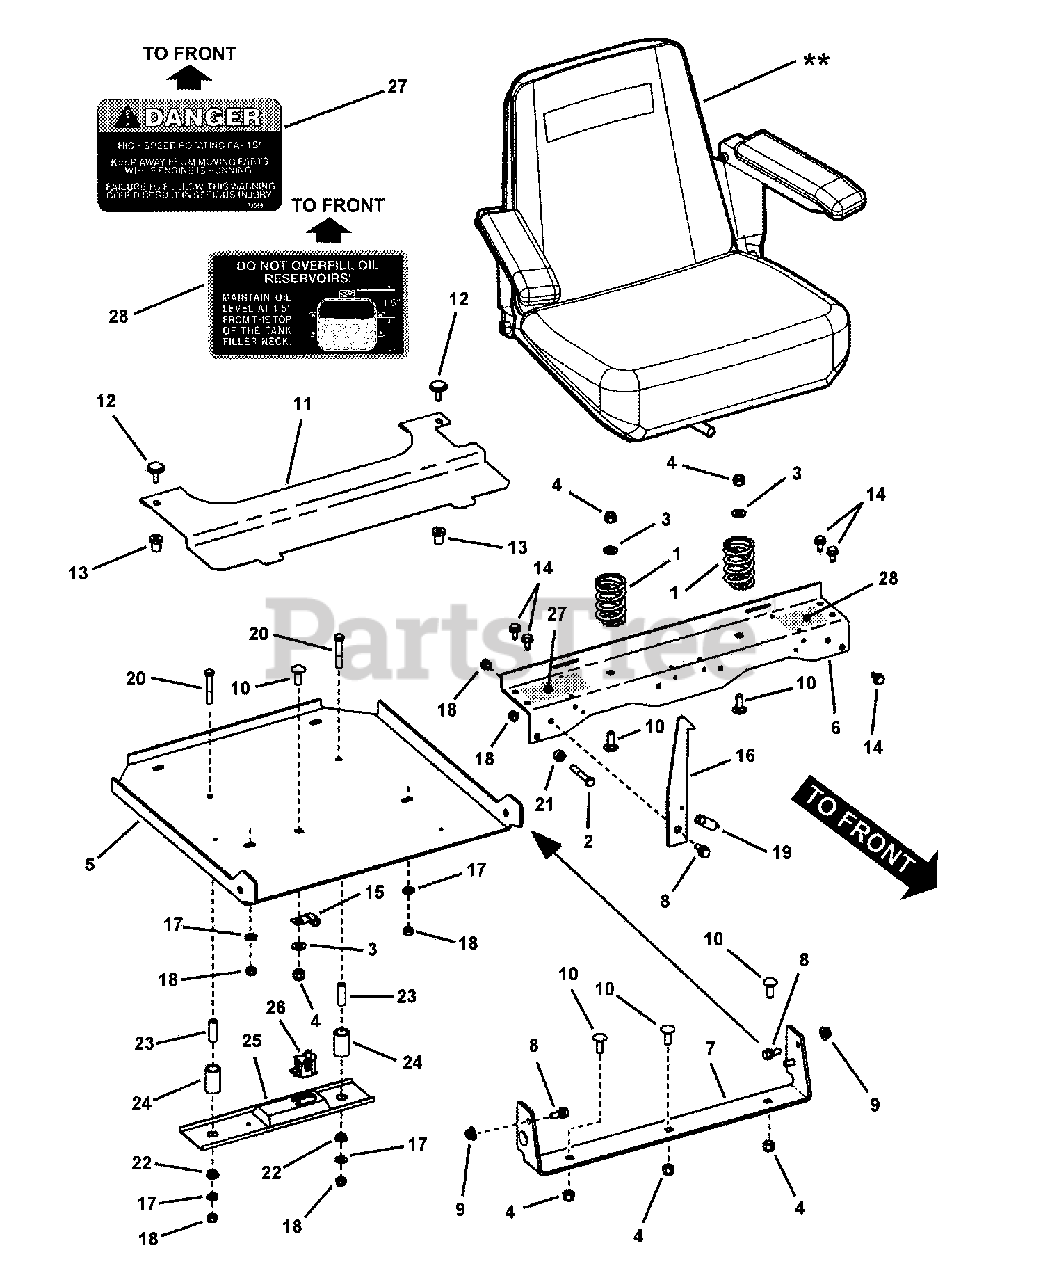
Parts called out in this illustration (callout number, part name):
1	SPRING, Compression- Seat Support
2	SCREW, 5/16-18 x 3/4" Hex Washer Self-Tap
3	WASHER, 3/8" Flat
4	NUT, 3/8-16 HEX NYLON LOCK
6	CROSSMEMBER, Seat
7	WELDMENT, Hinge Bracket
8	SHOULDER BOLT, 5/16-18
9	NUT, 5/16-18 Large Flange Hex Center Lock
10	BOLT, 3/8-16 x 1" Square Neck Carriage GR5
11	GUARD, Fan
12	KNOB, 1/4-20 x 3/4" Thread
13	WELL-NUT, 1/4-20 x 53/64"
14	SCREW, 5/16-18 x 5/8" Hex Washer Self-Tap
15	CLIP, Open J 3/8 Cushioned
16	LATCH, Seat
17	WASHER, 5/16" Flat
18	NUT, 5/16-18 HEX NYLON LOCK
19	SPRING, Extension
20	BOLT, 5/16-18 X 2", GD5
21	SPACER, .340 I.D.x .63 O.D. x .310 Thick
22	BUSHING, Seat
24	SPRING, Compression
25	HOLDER, Seat Switch
26	SWITCH, Seat, NC
27	DECAL, Warning
28	DECAL, Oil Reservoir Overfill Warning
